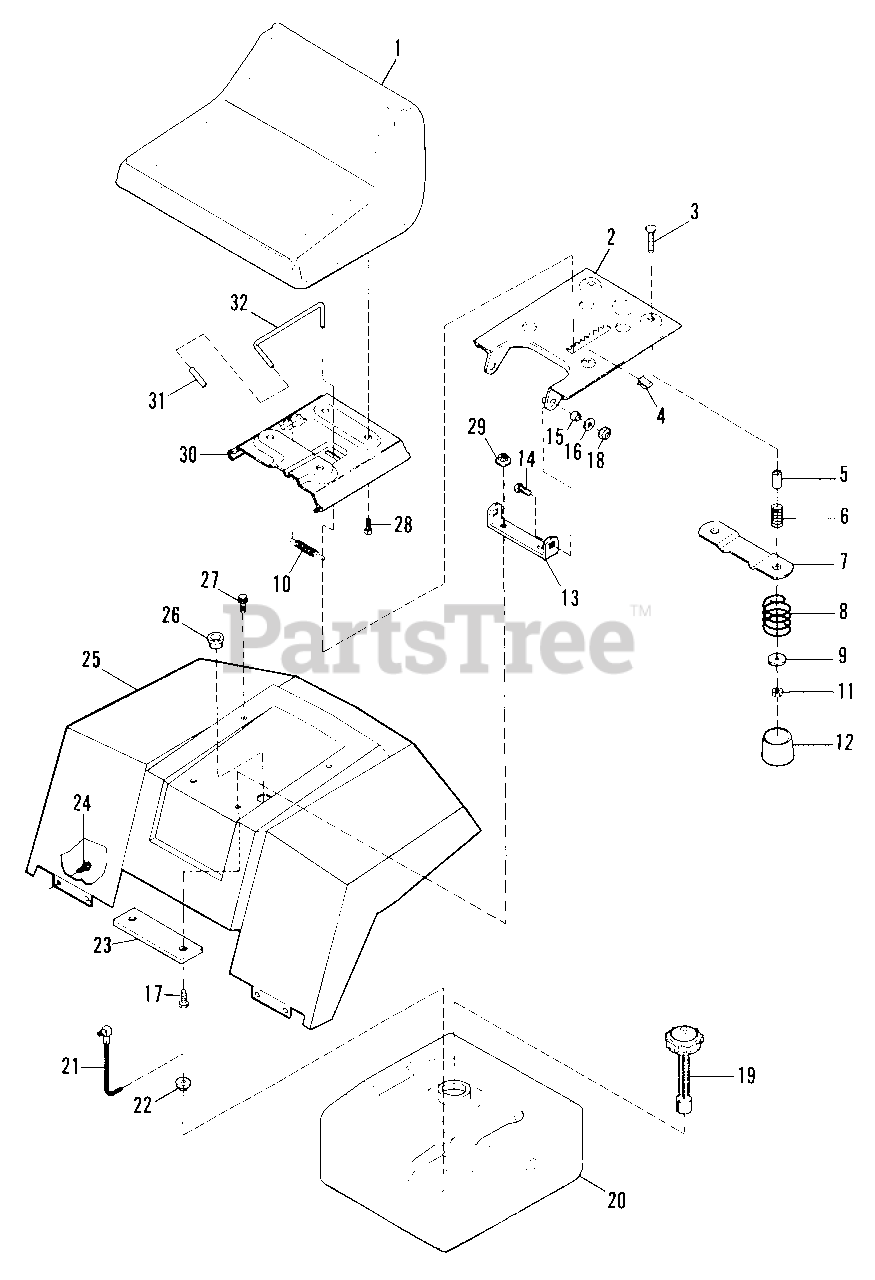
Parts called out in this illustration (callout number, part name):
2	SUPPORT, Seat Pivot
3	CARRIAGE BOLT, 5/16-18 x 1-3/4
4	CLIP, Speed
6	SPRING, Compression
7	PLATE, Switch
8	SPRING, Compression
9	WASHER, Plain
10	SPRING, Extension
11	NUT, Hex, Nylon Lock, 5/16-18
12	COVER, Spring
13	BRACKET, Seat Pivot
14	CARRIAGE BOLT, 3/8-16 x 1
16	WASHER, Plain, 13/32
17	SCREW, Truss Hd., Torx drive, 3/8-16 x 1
18	NUT, Hex, Nylon Lock, 3/8-16
19	CAP, Fuel Gauge
20	TANK, Fuel
21	ELBOW & TUBE ASSY.
23	PLATE, Reinforcement
24	SCREW, Taptite, 1/4-20 x 1/2
26	BUSHING, Snap
27	SCREW, Taptite, 5/16-18 x 5/8
28	BOLT, Hex, Whizlock, 5/16-18 x 5/8
29	NUT, Hex Flange Whizlock, 3/8-16
30	BRACKET, Seat Slide
31	HANDLE, Grip
32	LEVER, Seat Release
